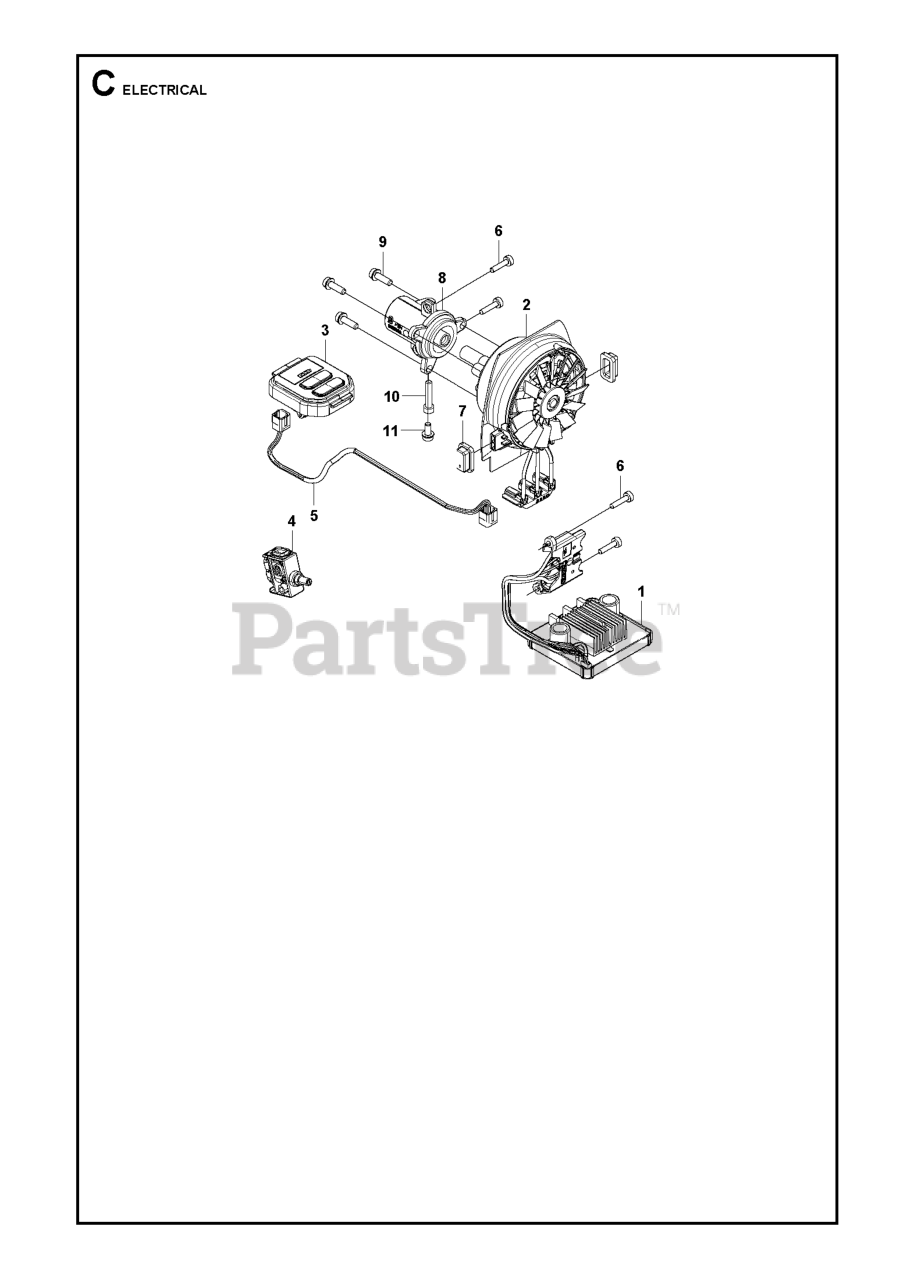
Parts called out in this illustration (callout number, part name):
1	CONTROL UNIT
1	CONTROL UNIT KIT 325ILK MECH
2	MOTOR ASSY ADAPTER
3	Controls
4	TRIGGER SWITCH IPX4
5	Wires
6	SCREW ITXSCT PW4.2X18 10.9 ZN
10	SCREW ITXSCM M5X25 T27 12.9 T
11	SCREW ITXSCM
